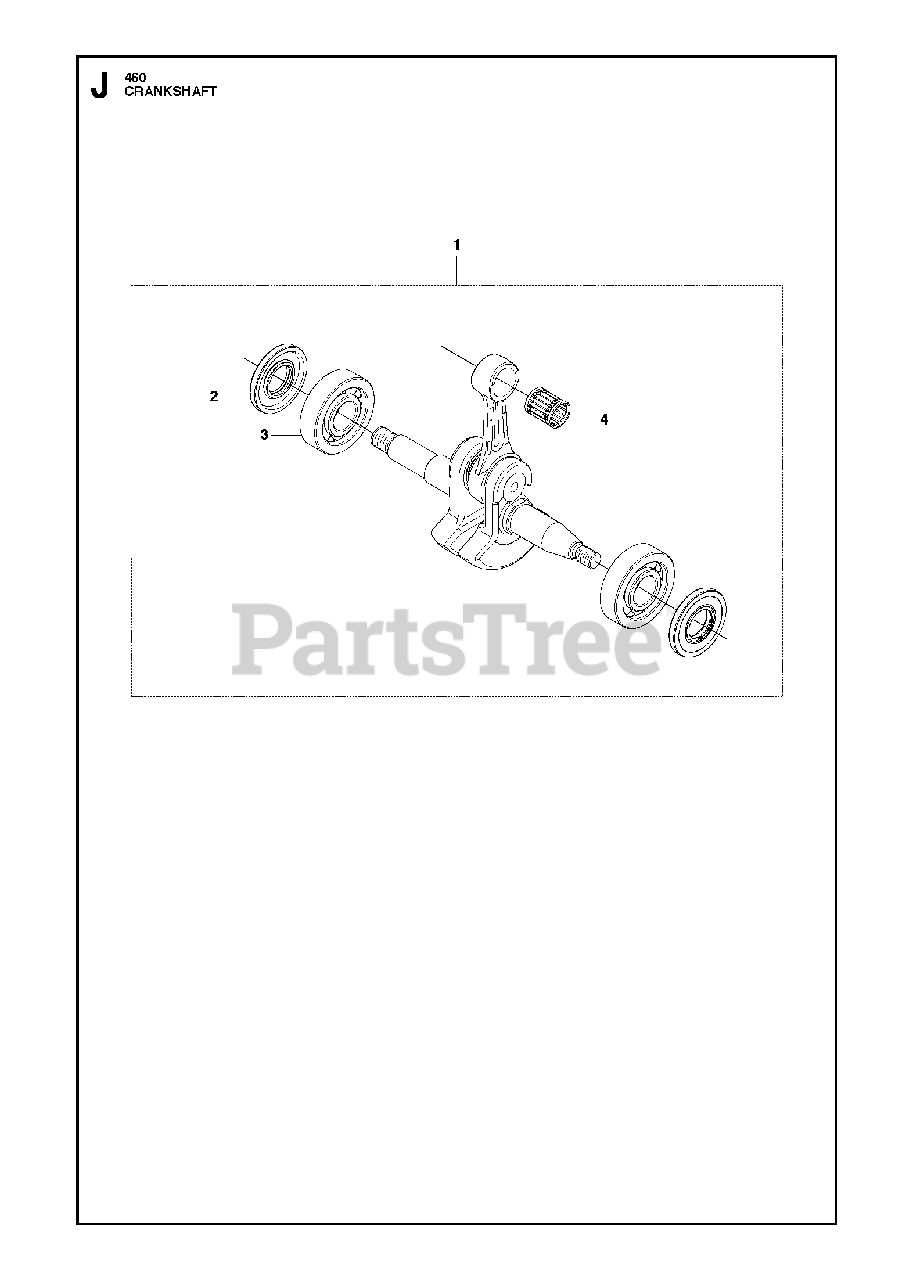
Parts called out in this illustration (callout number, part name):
1	RP CRANKSHAFT CPL
2	SEALING
3	BEARING
4	SUPPORT BUSHING
